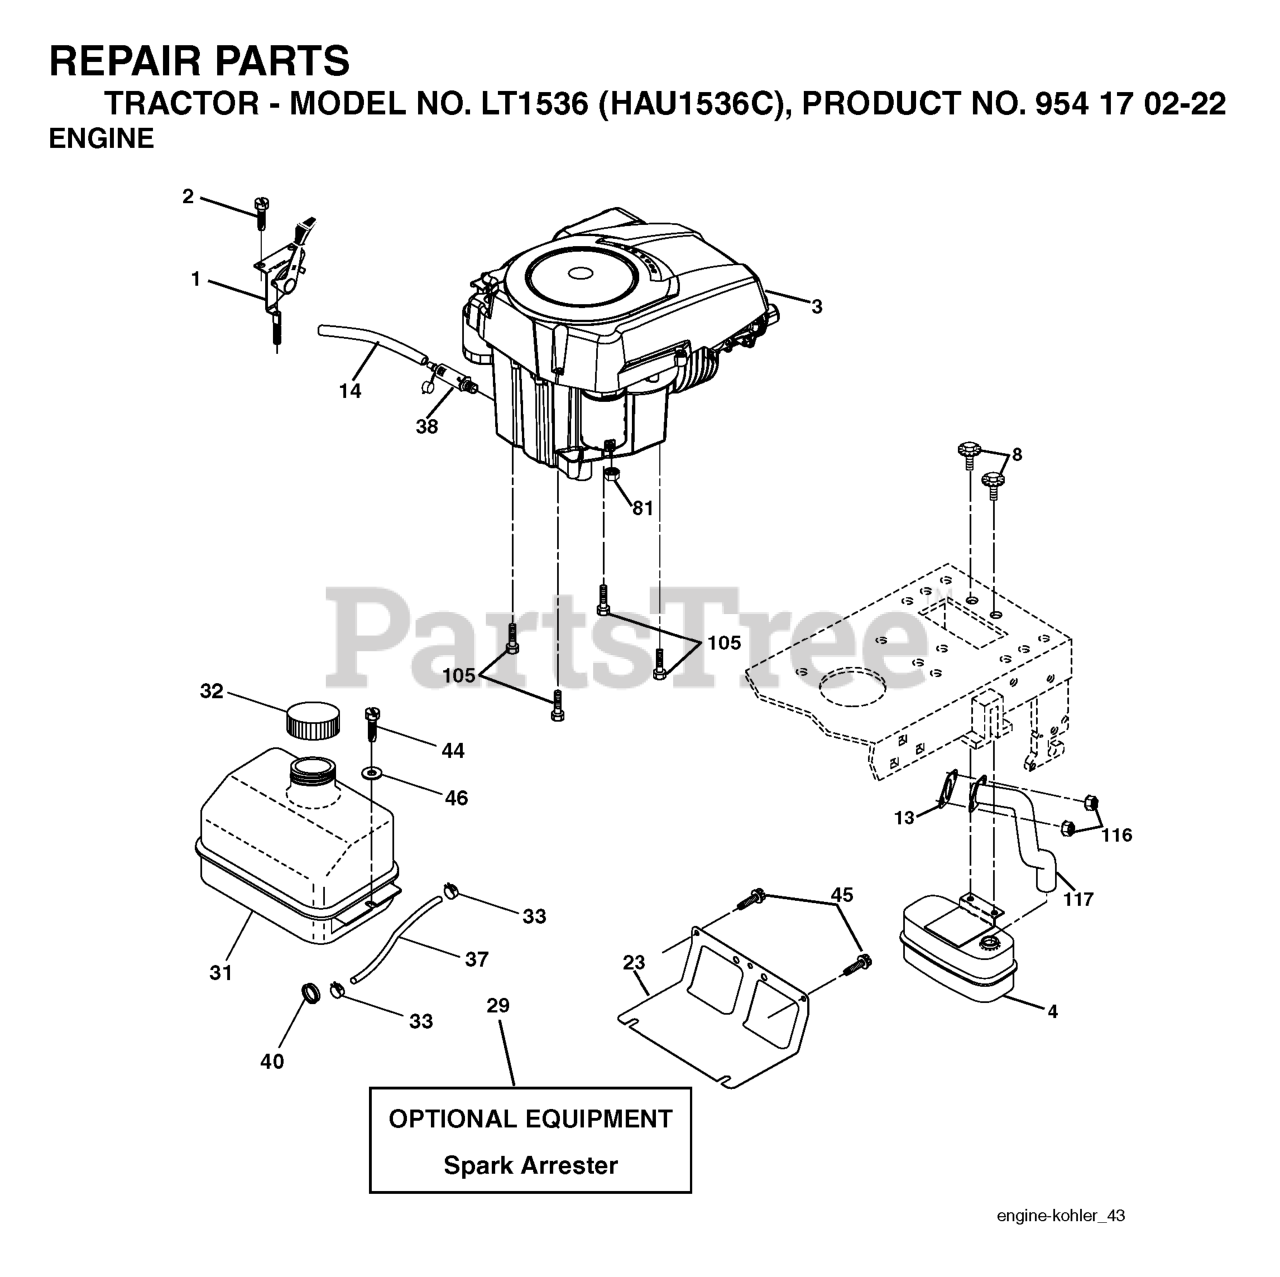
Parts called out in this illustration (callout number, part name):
1	CONTROL.THROTTLE.LT/YT
2	SCREW
4	MUFFLER.SINGLE.CYL.KOHL/B&S
8	BOLT.5/16-18UNCX3/4 W/SEMS.BLK
13	GASKET.EXHAUST.KOHLER
14	TUBE, DRAIN OIL ASM.
23	SHIELD.BROWNING.DBR.GUARD
29	KIT.SPARK ARRESTOR 794945 B&S
31	TANK.ASM.FUEL.FRONT.W/CAP
32	FUEL CAP
33	HOSE CLAMP
37	LINE.FUEL.20
38	PLUG DRAIN OIL EASY
40	BUSHING.SNAP.NYL.BLK.
44	SCREW HEXWSHR 1/4-20X3/4
45	SCREW, 3/8-16X3/4
81	NUT
105	SCREW 3/8-16X1
116	NUT.HEX.FLANGE.TOPLOCK
117	RP.TUBE.EXHAUST.KOHL.COURAGE
